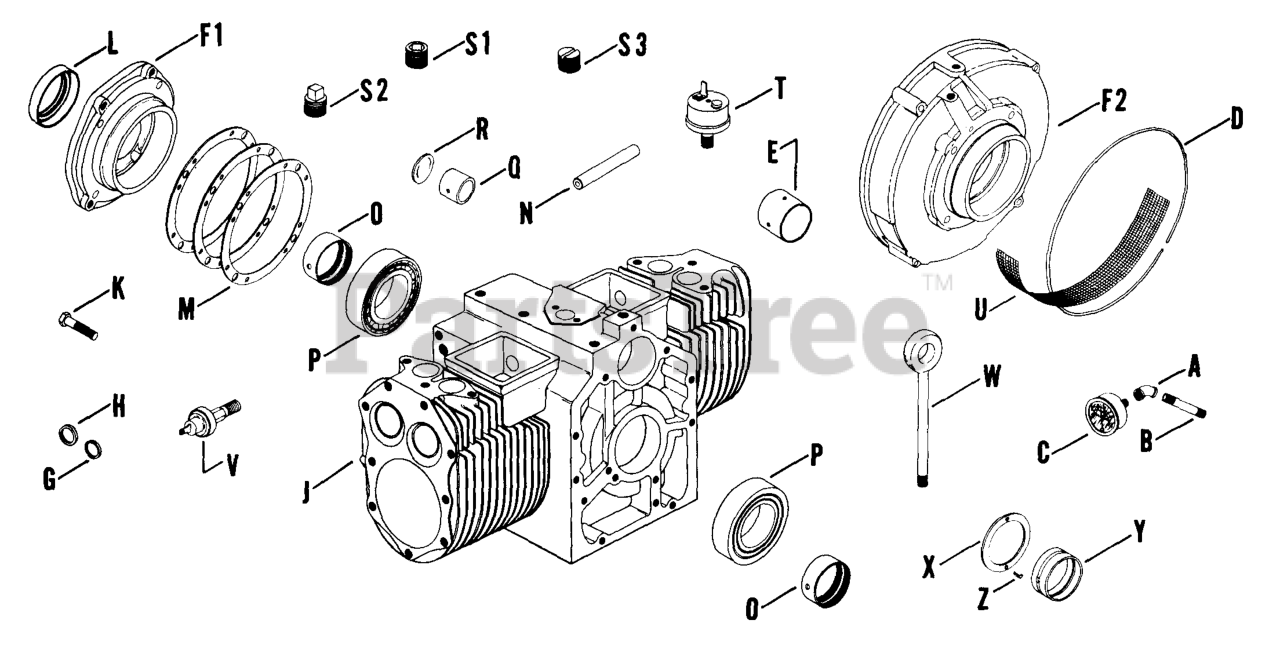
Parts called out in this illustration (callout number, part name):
E	BUSHING - DISCONTINUED
G	INSERT - DISCONTINUED
H	INSERT - DISCONTINUED
J	BLOCK - USE 49 005 01
K	SCREW - DISCONTINUED
L	SEAL - DISCONTINUED
M	SHIM - DISCONTINUED
N	GUIDE - DISCONTINUED
M	GUIDE - DISCONTINUED
O	SLEEVE - DISCONTINUED
O	SLEEVE .010 - DISCONTINUED
P	BEARING - DISCONTINUED
Q	BUSHING - DISCONTINUED
S1	PLUG, CTSK PIPE 1/8" USE 25 139 60-S
S2	PLUG, PIPE USE 25 139 52-S
